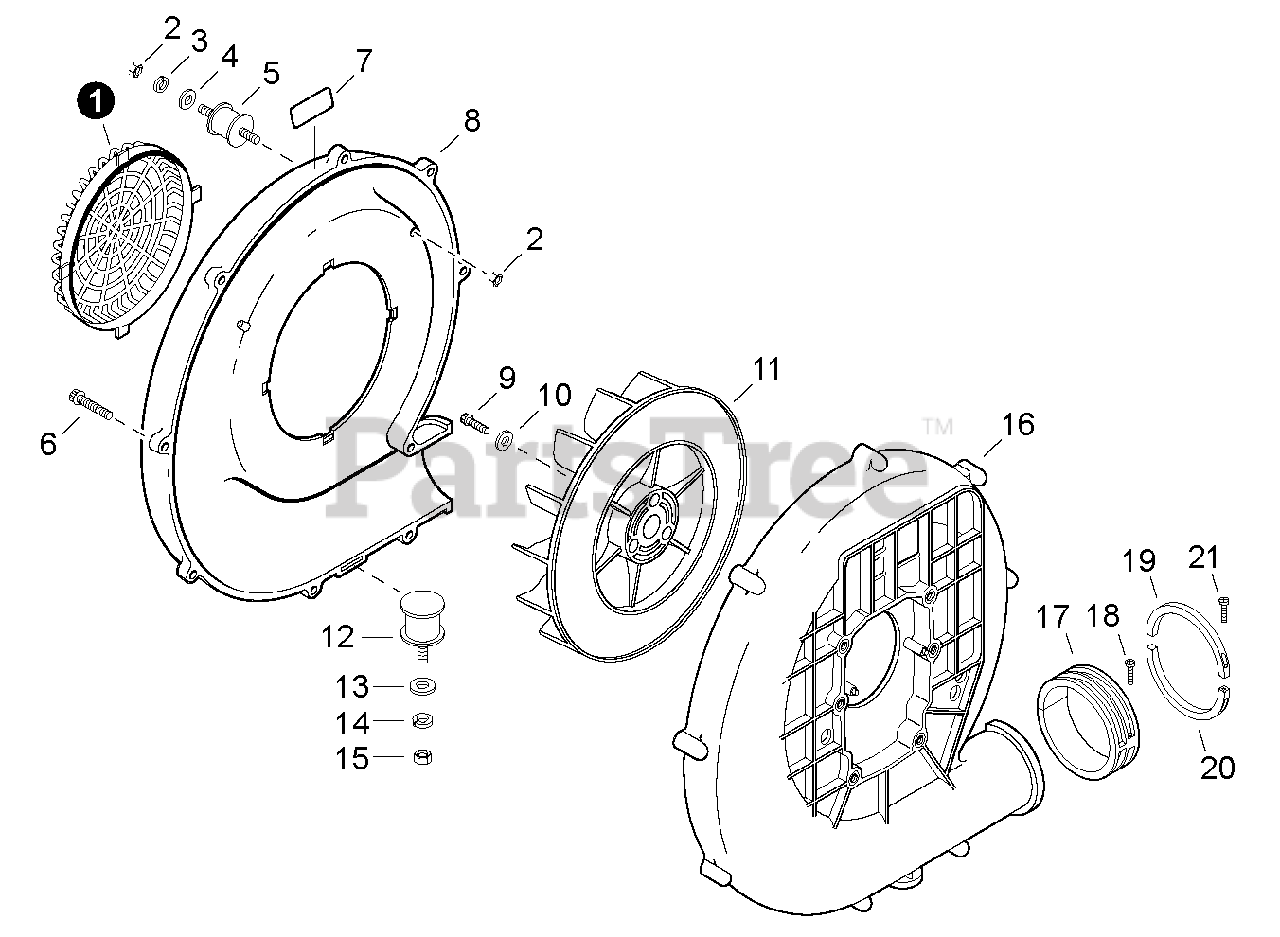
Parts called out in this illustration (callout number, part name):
1	GUARD, DEBRIS
2	NUT - 5
3	LOCKWASHER - 5
4	WASHER - 5
5	CUSHION
6	SCREW - 5 -- TAPPING
7	LABEL - NOISE
8	COVER, FAN - INNER
9	BOLT - 6
10	WASHER 6
11	FAN
12	CUSHION
13	COLLAR - 18
14	LOCKWASHER - 6
15	LOCKNUT - 6
16	COVER, FAN - OUTER
17	SLEEVE
18	SCREW - TAPPING
19	RING, RETAINING - A
20	RING, RETAINING - B
21	SCREW - 3X25
